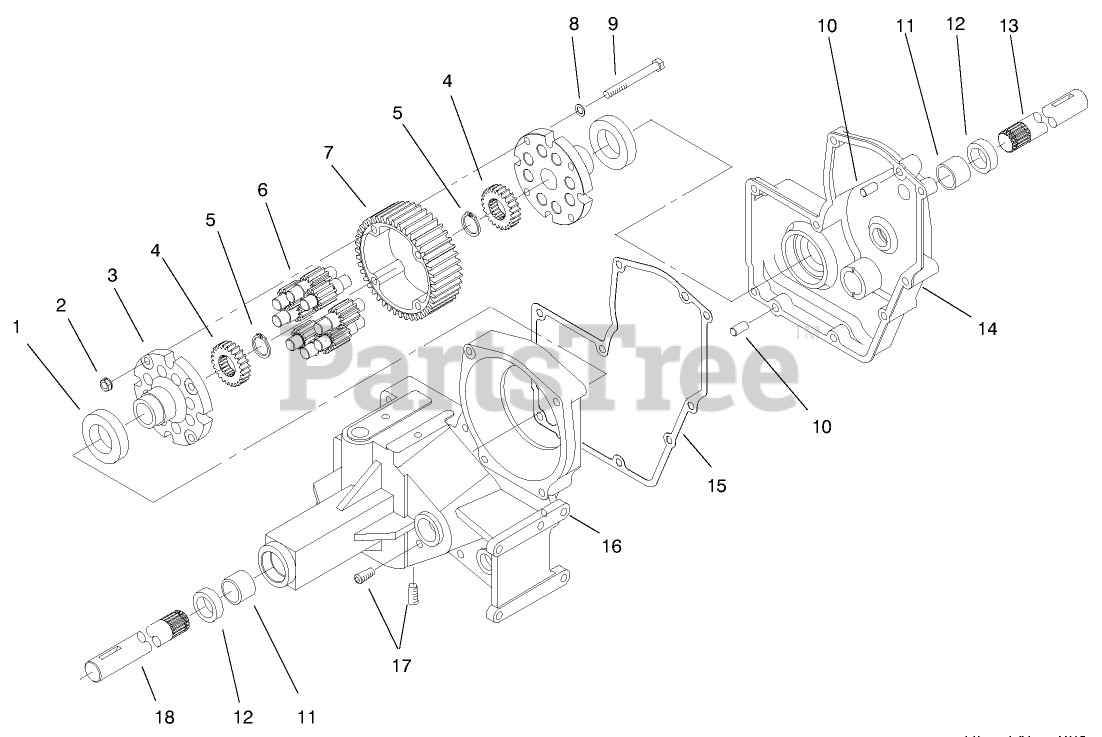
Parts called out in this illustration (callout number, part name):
1	BEARING-BALL
2	NUT-HEX
3	END CAP-DIFFERENTIAL
4	GEAR-AXLE DIFFERENTIAL
5	RING-SNAP
6	GEAR-PINION, 11T
7	GEAR-DIFFERENTIAL RING, 43T
8	WASHER
10	PIN-LOCATING
11	BEARING
12	SEAL-OIL
14	Case-Transaxle
15	GASKET-TRANSMISSION
16	CASE-TRANSMISSION RH
16:2	DECAL - DANGER
